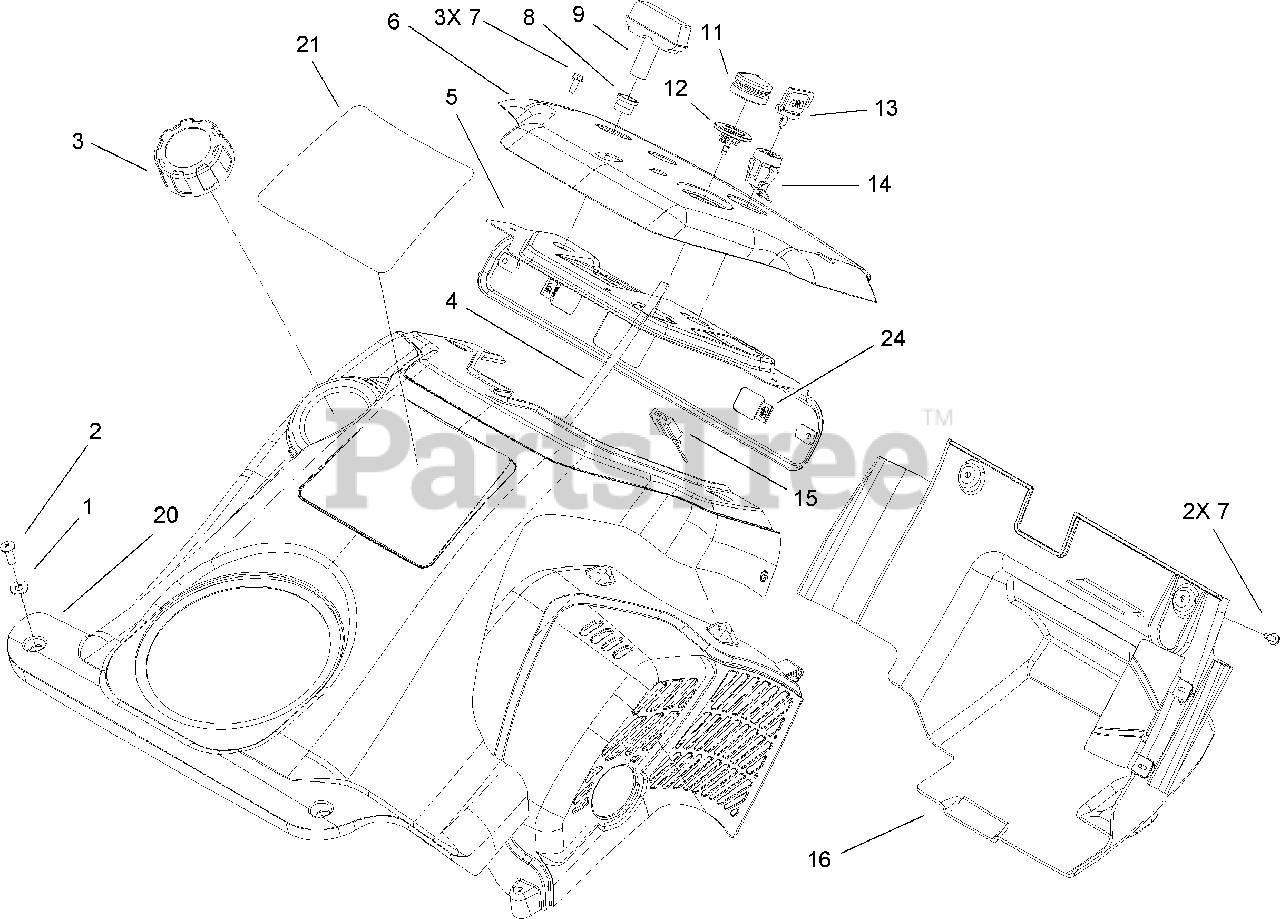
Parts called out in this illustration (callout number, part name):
1	WASHER-FLAT
2	SCREW-PPH
3	GAS CAP ASM
4	HOSE-PRIMER
5	PANEL-SUPPORT, CONTROL
6	PANEL-CONTROL
7	SCREW-HWH
8	GUIDE-ROPE, STARTER
9	HANDLE-RECOIL
11	BULB-PRIMER
12	BODY-PRIMER
15	CONNECTOR-BODY
16	LOWER SHROUD AND BAFFLE ASM
20	UPPER SHROUD ASM
24	NUT-SPEED
